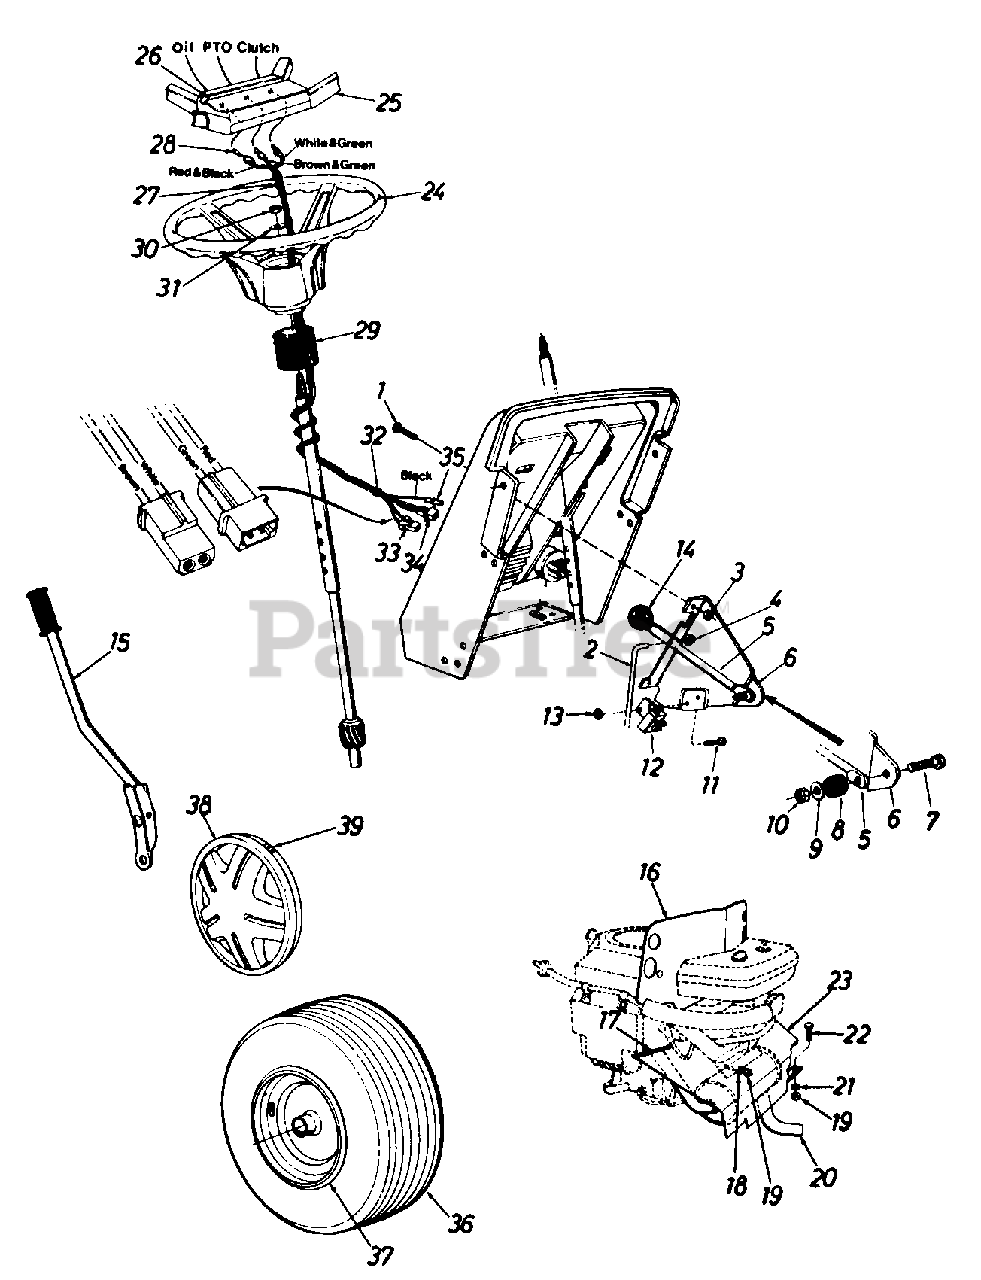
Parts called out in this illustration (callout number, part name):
1	Truss Mach. Scr. 1/4-20 x .5" Lg.
2	Deck Control Rod
3	Hex Sems Nut 1/4-20 Thd.
4	Push Cap
5	PTO Lever
6	Deck Clutch Cont. Brkt.
7	Hex Bolt 1/4-20 x 1.25" Lg.
8	Rubber Washer
9	Fl-Wash. .281" I.D. x .73" O.D.
10	Hex L-Nut 1/4-20 Thd.
11	Truss Mach. Scr. #10-24 x .5" Lg.
12	Safety Switch
13	Hex Nut #10-24 Thd.
14	Knob-Blade Clutch
15	Lift Handle Ass'y.
16	Top Heat Shield
17	Trim Strip 10" Lg.
18	L-Wash. 5/16n I.D.
19	Hex Nut 5/16-18 Thd.
20	Muffler
21	L-Wash. 5/16" I.D.
22	Hex Bolt 5/16-18 x .75" Lg.
23	Front Heat Shield
24	Steering Wheel
25	Steering Wheel Insert
26	Steering Wheel Insert Label
27	Wire Harness
28	Bulb
29	Steering Bellow
30	Hex L-Nut 5/16-24 Thd.
31	Bell-Wash. .345" I.D. x .88" O.D.
32	Clamp
33	Connector
34	Connector
35	Connector
36	Wheel Ass'y. Comp.
37	Rim Only
38	Hub Cap
39	Spring Clip
